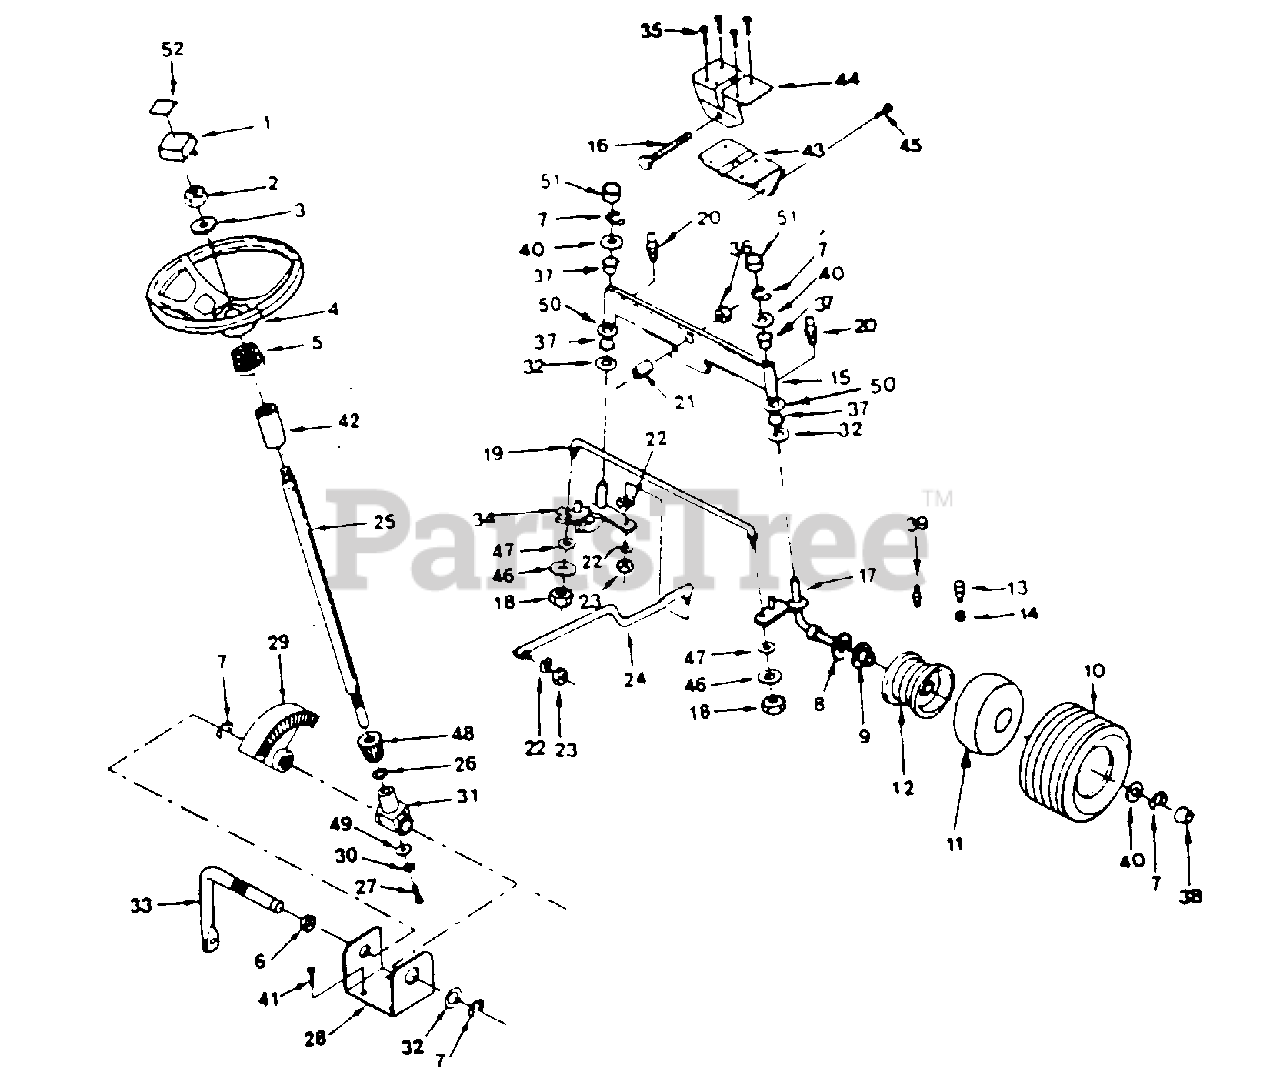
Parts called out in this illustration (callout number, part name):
1	Steering Wheel Insert (AYP part number)
2	Toplock Jam Hex Nut (AYP part number)
3	Washer (AYP part number)
4	Steering Wheel (AYP part number)
5	Steering Wheel Adaptor (AYP part number)
6	Snap-In Nyliner (AYP part number)
7	Klip Ring (AYP part number)
8	Washer (AYP part number)
9	Front Wheel Bearings
10	Tire (AYP part number)
11	Tube (Not furnished w/Tractor)
12	6 "Front Rim Assembly (AYP part number)
13	Valve Stem (AYP part number)
14	Value Cap (AYP part number)
15	Front Axle Assembly (AYP part number)
16	Hex Bolt (AYP part number)
17	R.H. Spindle Assembly (AYP part number)
18	Hex Nut (AYP part number)
19	Tie Rod (AYP part number)
20	Grease Fitting (AYP part number)
21	Front Axle Bearing Spacer (AYP part number)
22	Lock Washer 3/8 (AYP part number)
23	Hex Nut 3/8-24 (AYP part number)
24	Drag Link (AYP part number)
25	Steering Shaft (AYP part number)
26	Washer (AYP part number)
27	Socket Hex Screw (AYP part number)
28	Steering Bracket Assembly (AYP part number)
29	Sector Gear (AYP part number)
30	Lock Washer (AYP part number)
31	Shaft Support (AYP part number)
32	Thrust Bearing (AYP part number)
33	Pitman Shaft (AYP part number)
34	L.H. Spindle Assembly (AYP part number)
35	Thd. Form Washer Hd. Hex Screw (AYP part number)
36	Flange Nut (AYP part number)
37	Bearing (AYP part number)
38	Front Hub Cap (AYP part number)
39	Grease Fitting (AYP part number)
40	Washer (AYP part number)
41	Thd. Form. Washer Hd. Hex Screw (AYP part number)
42	Steering Shaft Tube (AYP part number)
43	Front Saddle Support (AYP part number)
44	Rear Saddle Support (AYP part number)
45	Thd. Roll. Washer Hd., Hex Screw (AYP part number)
46	Lock Washer (AYP part number)
47	11/32 x 3/4 x 16 Ga. (AYP part number)
48	Pinion Gear (AYP part number)
49	Washer (AYP part number)
50	Washer (AYP part number)
51	Spindle Cap (AYP part number)
52	Steering Decal (AYP part number)
